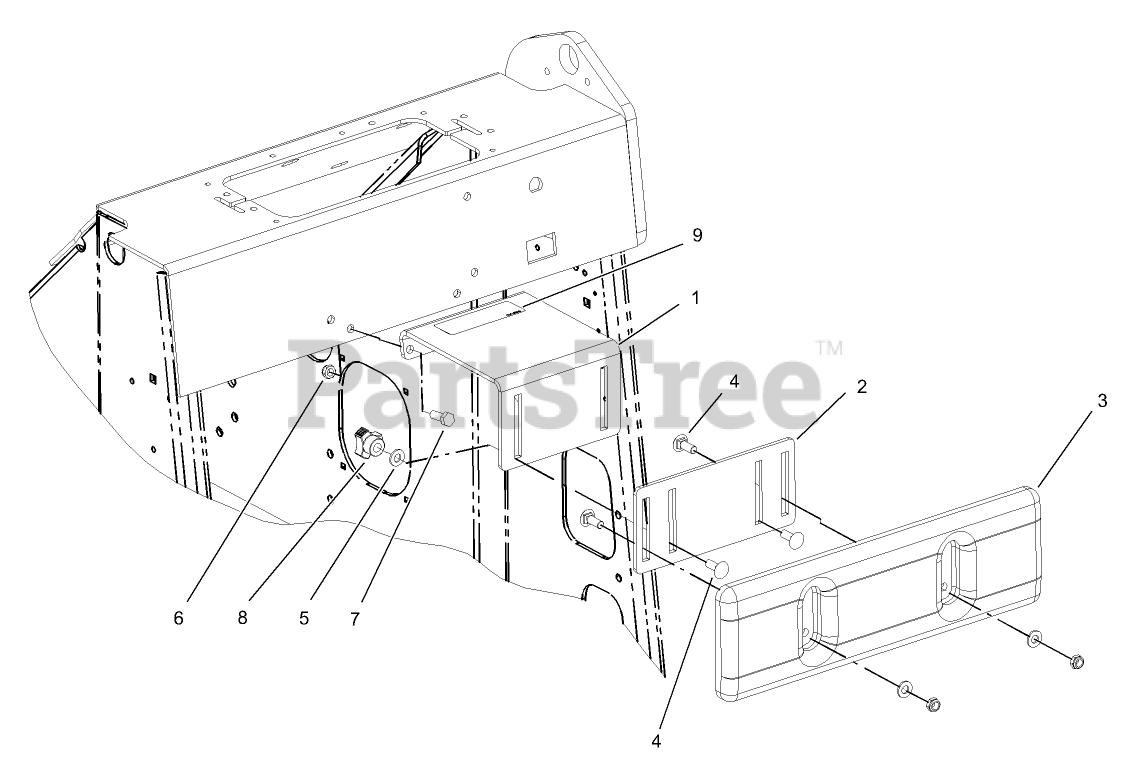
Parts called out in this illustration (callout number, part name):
1	Thigh Support ASM
2	PLATE-ADJUSTING
3	SUPPORT-THIGH
4	SCREW-CARR
5	WASHER-FLAT
6	NUT-LOCK, NI
7	SCREW-HH
8	Knob-Adjustment
9	DECAL-MANUAL
